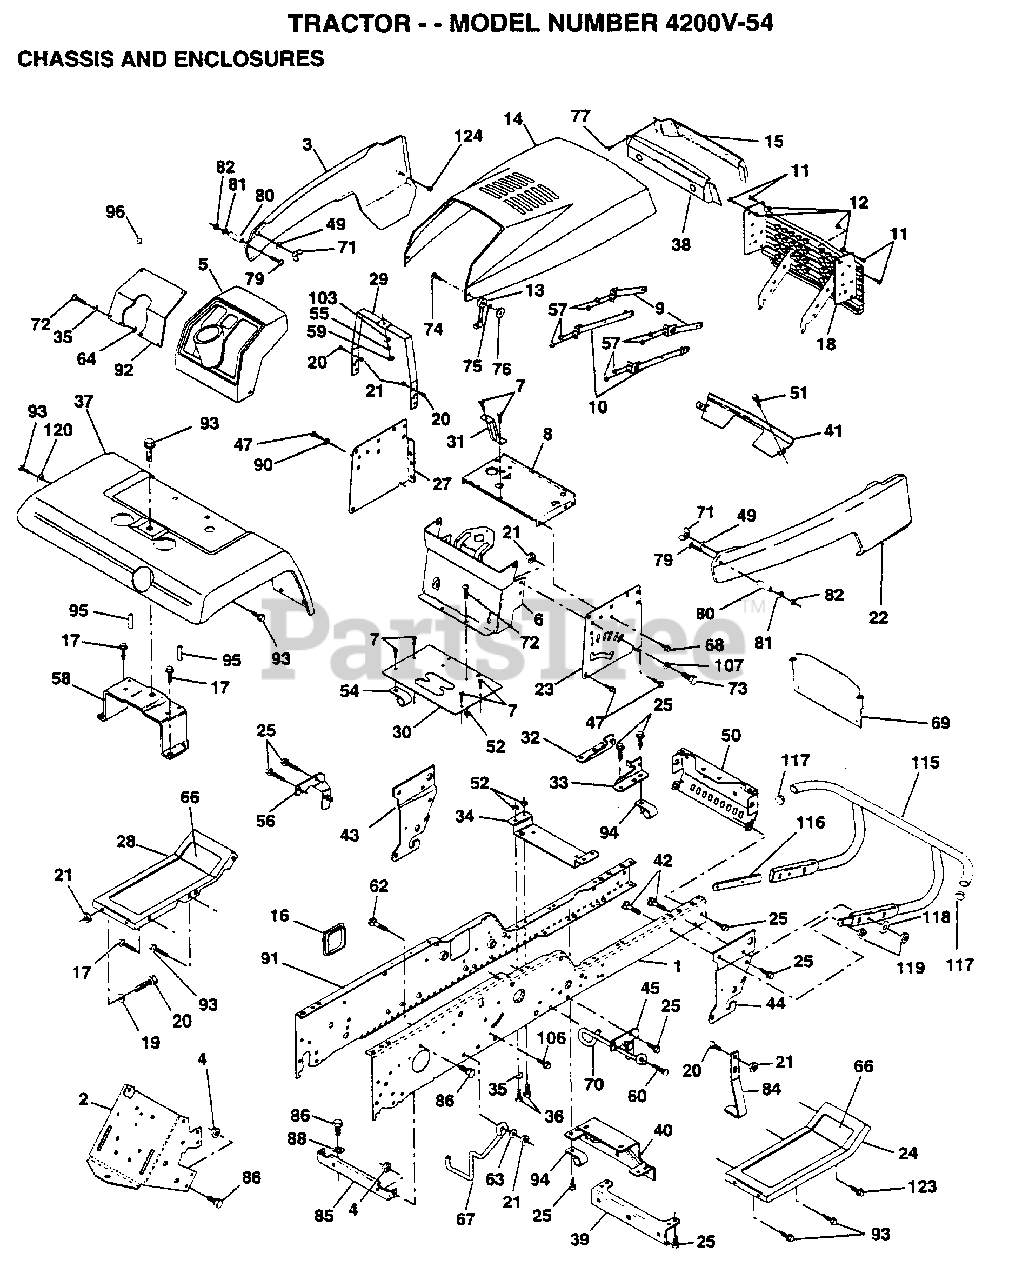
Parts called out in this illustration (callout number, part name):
2	DRAWBAR GT
3	PANEL SIDE LH
4	NUT.7/16
5	DASHBOARD BLACK
6	DASH ASM LOWER
7	SCREW
8	SUPPORT BATRY VGT
12	NUT
13	HOOD LATCH T
15	LENS.BAR.CLEAR
16	COVER ACCESS
17	SCREW
19	WASHER
20	BOLT
25	SCREW
29	DASH.SUPT.YP/HUSQ
30	SADDLE SILKSCRN
31	BRACE.SUPT.STRG
32	BRACKET ASM FRAME
33	BRACKET ASM FRAME
34	BRACKET.ENG.SUPT.
35	WASHER
36	BOLT
39	BRACKET.AXLE.FRT.
41	STRAP.GRILLE.424
43	BRACKET.SUS.FT.LH
44	BRACKET.SUS.FT.RH
47	SCREW LT
49	WASHER
50	BRACKET.CHASSIS.
51	SCREW CRT
54	"CLIP,INSULATOR"
55	WASHER PM
57	NUT
58	BRKT.ASM.FENDER
60	SCREW
62	BOLT D
63	WASHER
66	FOOTREST PAD
67	GUIDE BELT TRANS
68	SCREW LT
69	SHIELD.HEAT.VGT.
70	GUIDE.BELT.MID.SP
72	SCREW
73	BOLT
74	SCREW
75	LOCKWASHER
76	WELDNUT
79	SCREW
80	SPACER LT
81	WASHER
84	STOP.OVER.CENTER
86	BOLT
88	LOCKWASHER
90	LOCKWASHER
92	PLATE DASH SILKSC
93	SCREW LT
94	CLIP GTV
95	NUT-PUSH YT
96	PLUG-DASH T
103	LOCKWASHER
107	WASHER
115	BUMPER.ASM.W/PY
116	BRACKET.EXT.BUMP.
117	PLUG.PLASTIC
118	WASHER
120	WASHER HYT
123	SCREW GTV
124	PAL NUT LT
